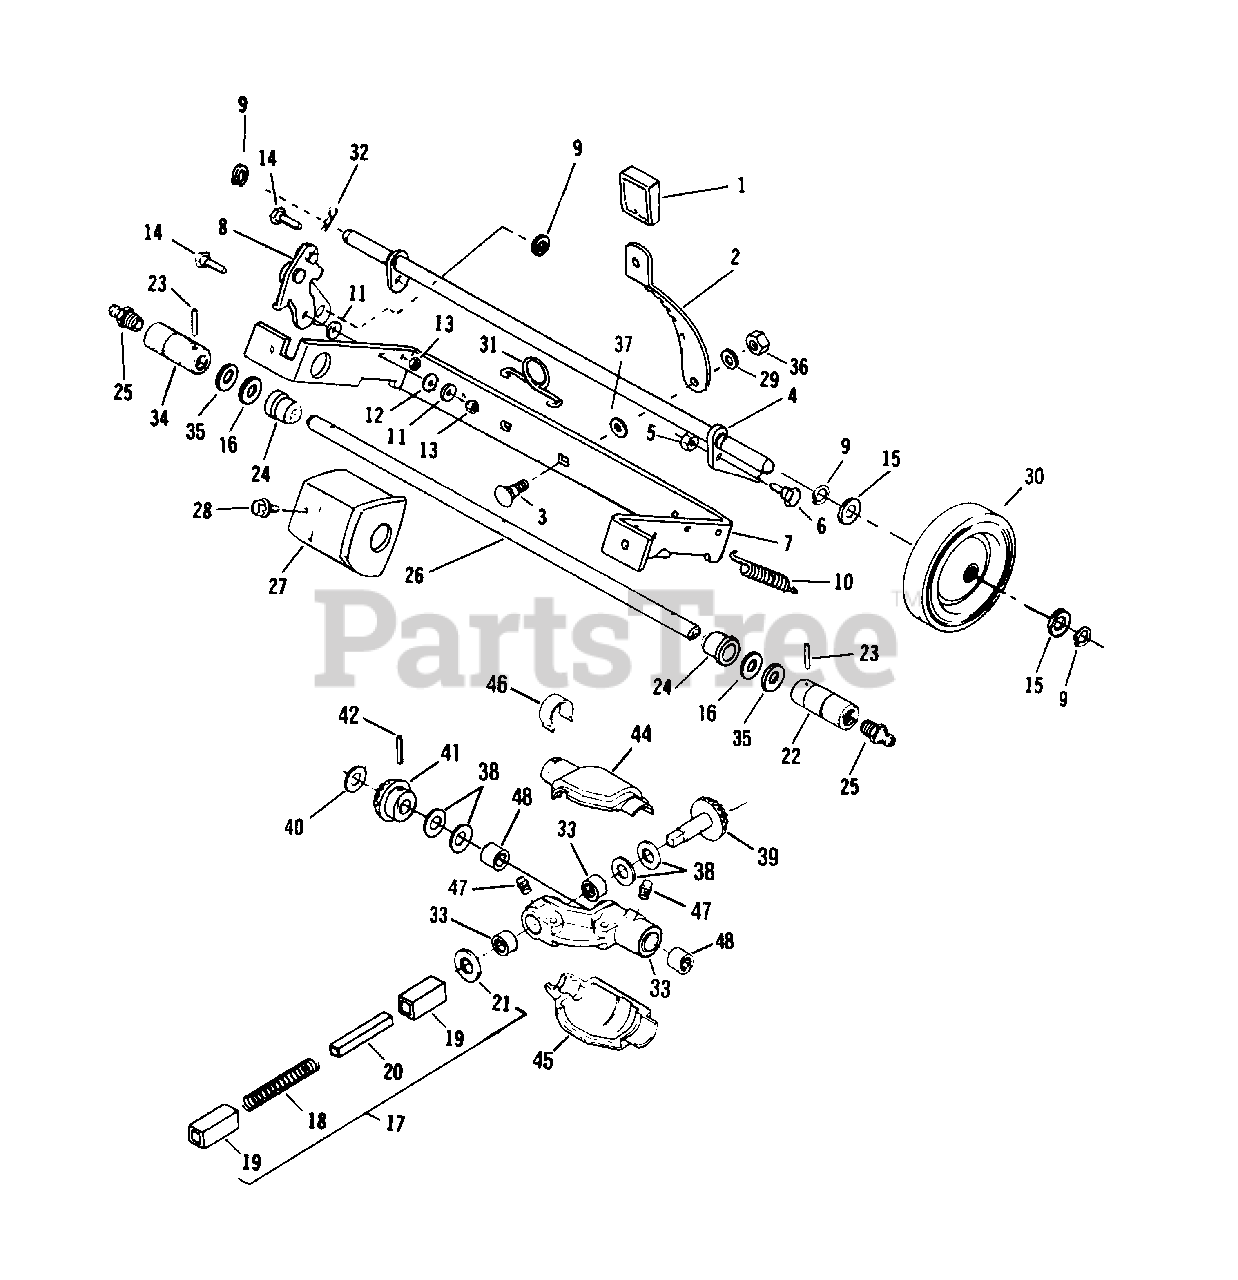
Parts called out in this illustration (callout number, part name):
1	Knob-Rear Height Adjust Lever
2	Lever-Rear Height Adjust
3	Shoulder Bolt-Hgt. Adjust Lever
4	Axle Assembly
5	Locknut
6	Bolt-Shoulder
7	Bracket-21" Axle
8	Clutch Assembly
9	Retaining Ring
10	Spring
11	Washer
12	Lockwasher
13	Stopnut
14	Bolt-Shoulder
15	Washer
16	Washer
17	Driveshaft Assembly
18	Spring-Compression
19	Bushing-Driveshaft
20	Driveshaft
21	Washer
22	Drive Roller-L.H.
23	Pin-Groove
24	Sleeve and Bearing Assembly
25	Grease Fitting
26	Shaft
27	Guard-Roller
28	Screw
29	Washer
30	Wheel-Rear
31	Spring-Height Adjust
32	Lock Pin
33	Bracket and Bearing Assembly
34	Drive Roller-R.H.
35	Spacer
36	Locknut
37	Washer-Height Adjust Lever
38	Washer
39	Gear-Drive
40	Washer
41	Gear-Driven
42	Spring Pin
43	Bearing
44	Upper Gear Cover
45	Lower Gear Cover
46	Clamp
47	Zerk Fitting
48	Bearing
